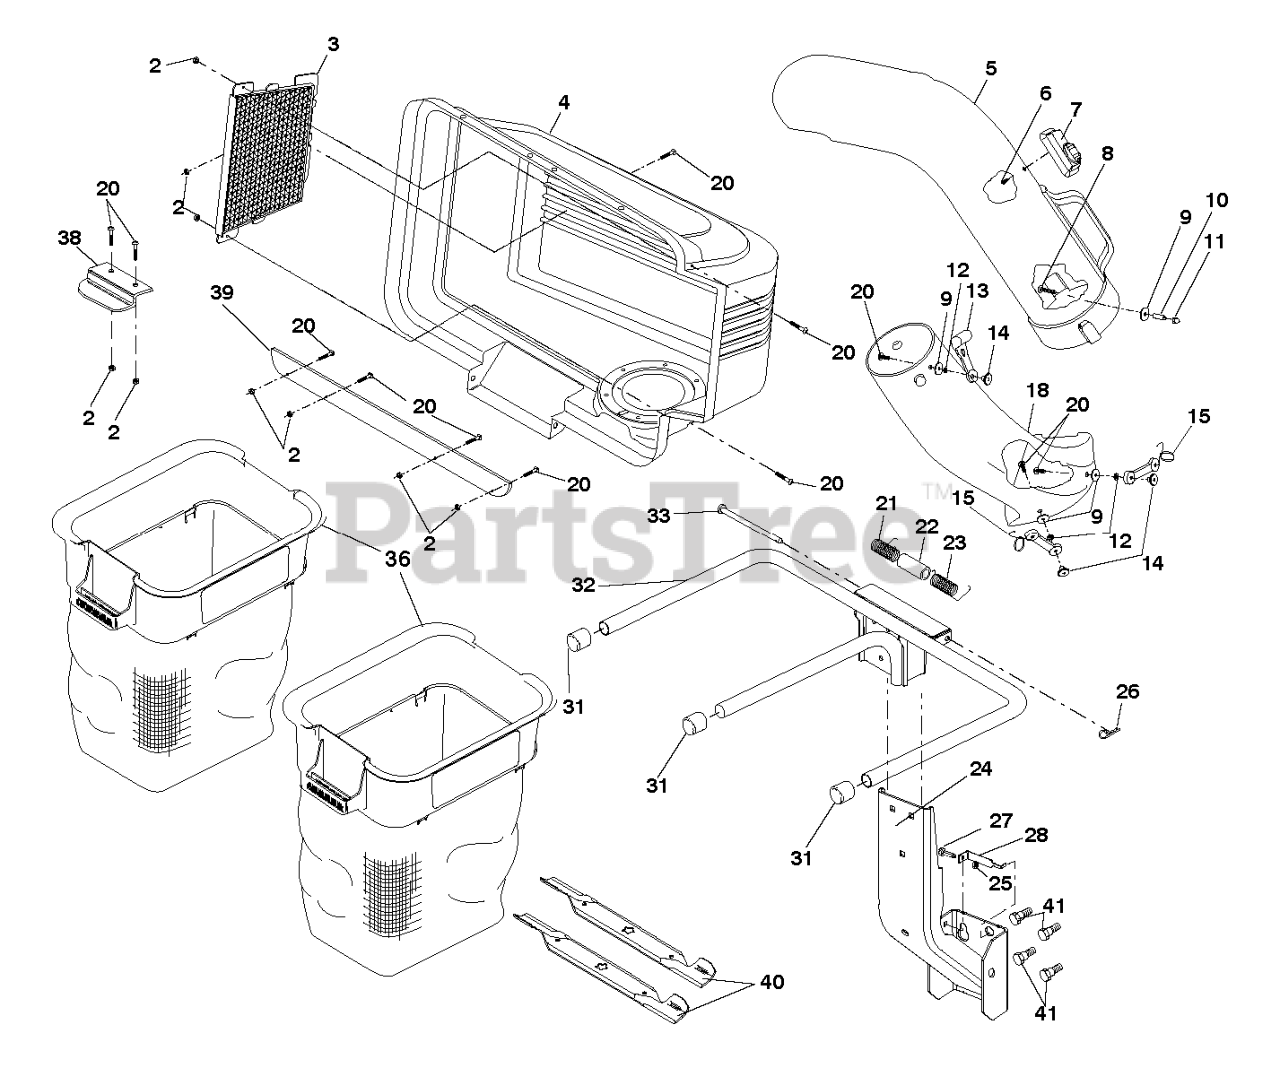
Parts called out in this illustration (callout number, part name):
3	COVER SCREEN
4	COVER.ASM.BAG.W/STRIP
5	CHUTE.UPPER.42"
7	INDICATOR ASM BAG
8	SCREW
9	RP STEEL WASHER
11	NUT
12	LOCKWASHER #10
13	LATCH.HOOD.
14	WELDNUT
15	LATCH ASSY
18	LOWER CHUTE FOR 38" BAGGER
20	SCREW
21	SPRING COVER LH
22	SPACER.COVER.BAGGER
23	SPRING COVER RH
24	POST.SUPPORT.BAGGER.BLACK
25	NUT.1/4-20.HEX.NYLOC.ZD
26	RETAINER-SPRNG RB
28	STOP BRACKET, BAGGER 2 BIN
31	PLUG, TUBING END
32	FRAME.ASM.BAGGER.2BIN.QC42B
33	BAGGER.HINGE.PIN
36	CONTAINER BAG, SOFT
38	LATCH CER38
39	STRIP.REINFORCE.BAGGER.2BIN.BL
40	BLADE.HI.LIFT.38"
41	SHOULDER BOLT 5/16-18TT
